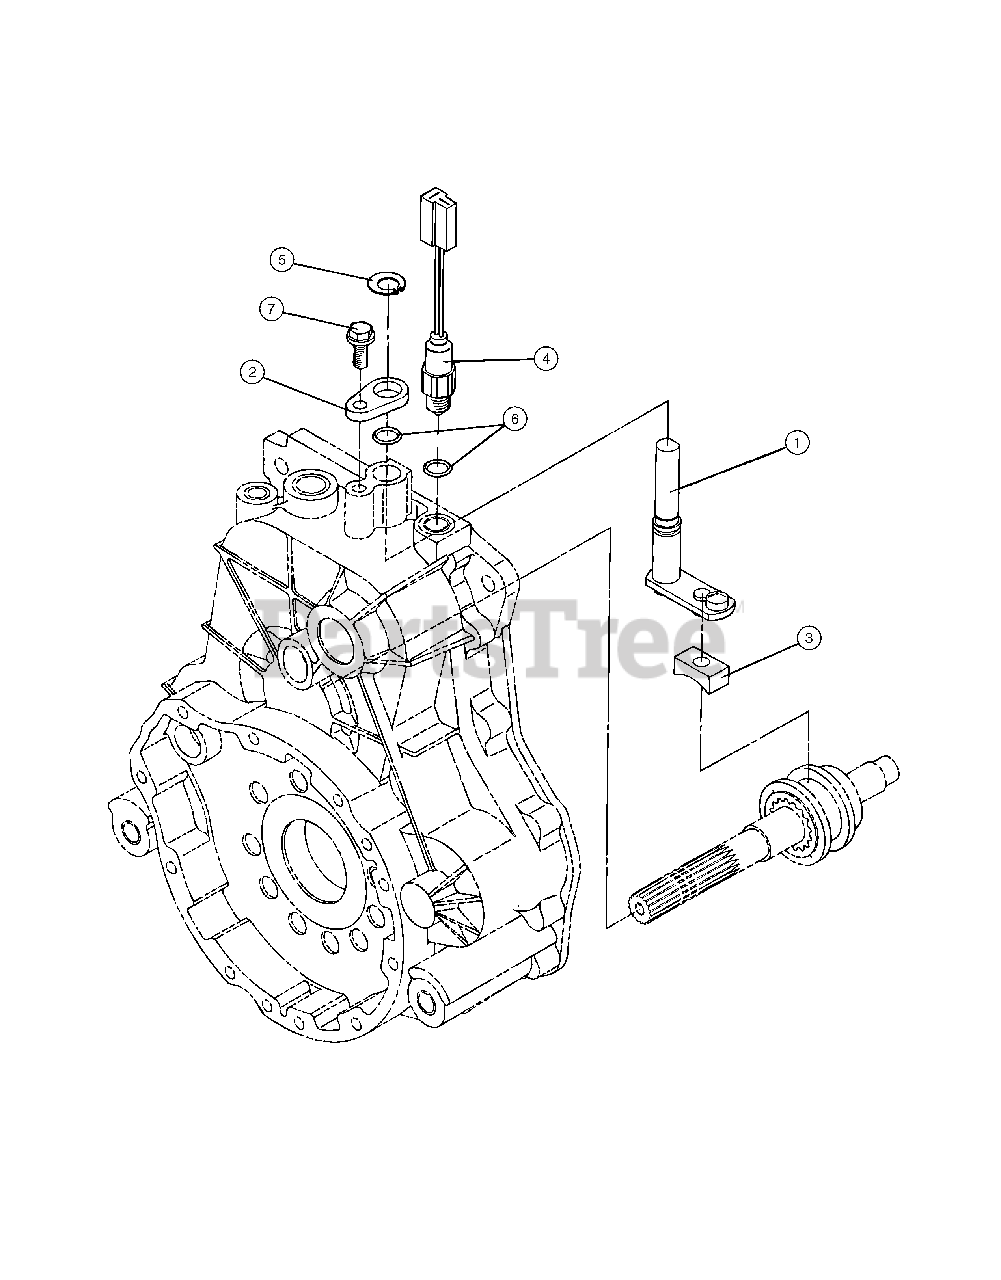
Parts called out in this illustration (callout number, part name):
2	Plate
5	Ring, 14
6	Packing, P 12.5
7	Tapping Screw, 8 x 20
